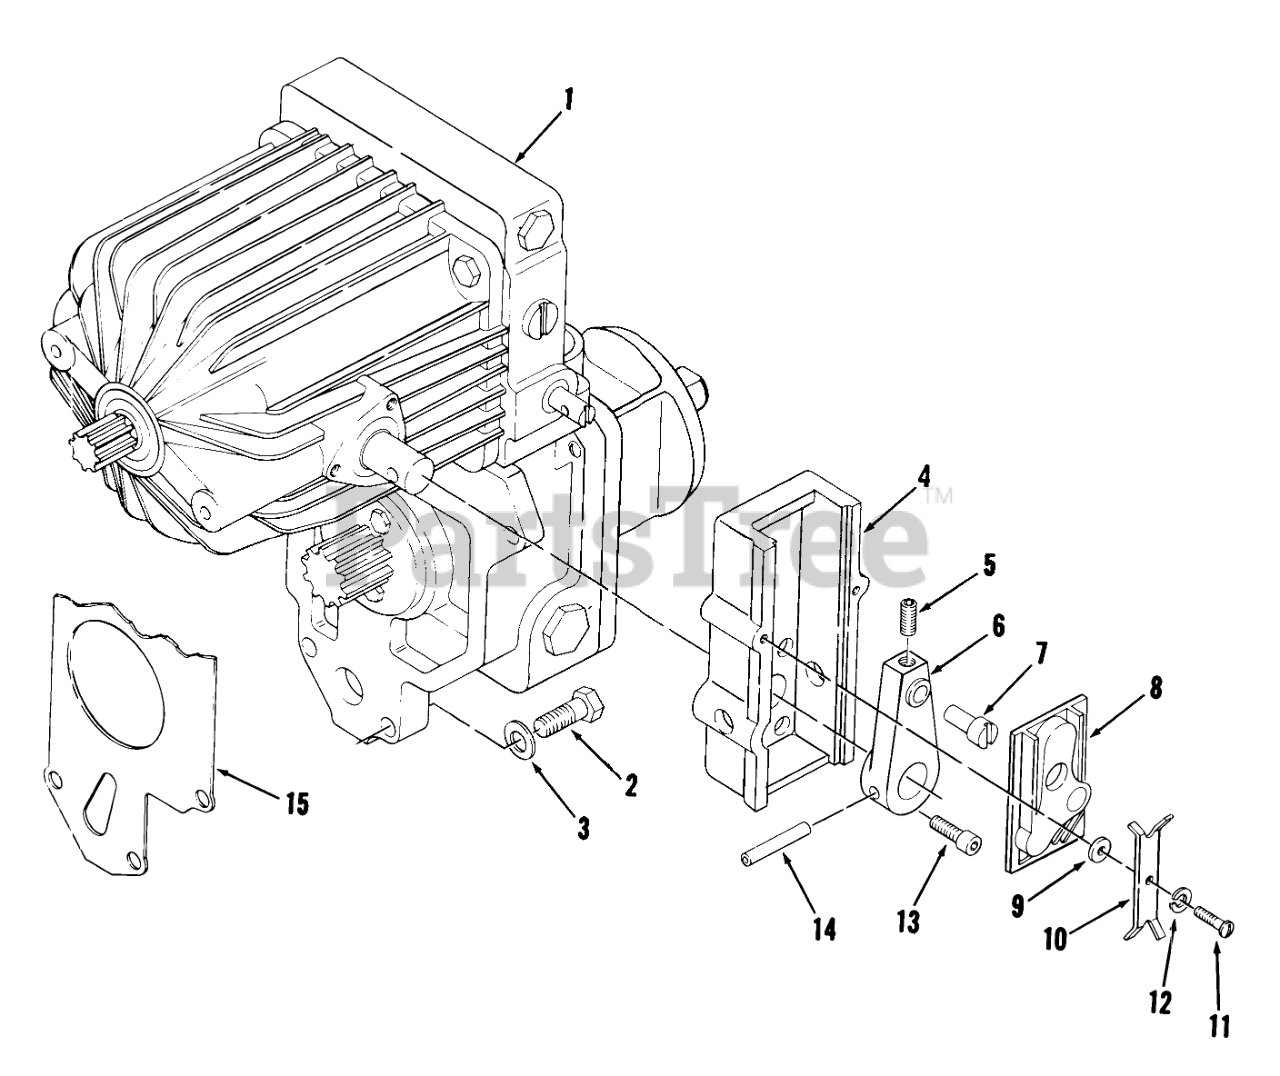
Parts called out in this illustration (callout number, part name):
1	Pump & Motor C-121 Only
1	Trans Assembly Piston To Piston-Complete
2	BOLT
3	Washer
4	SUPPORT CAM BLOCK
6	Belt Guide
7	ECC CAM FOLLOWER
8	CAM
9	WASHER
10	TENSION PLATE
11	SCREW
12	LOCKWASHER
13	SHCS 1/4-20 X 1/2
14	PIN-ROLL 1/4 X 1 1/4
15	GASKET
